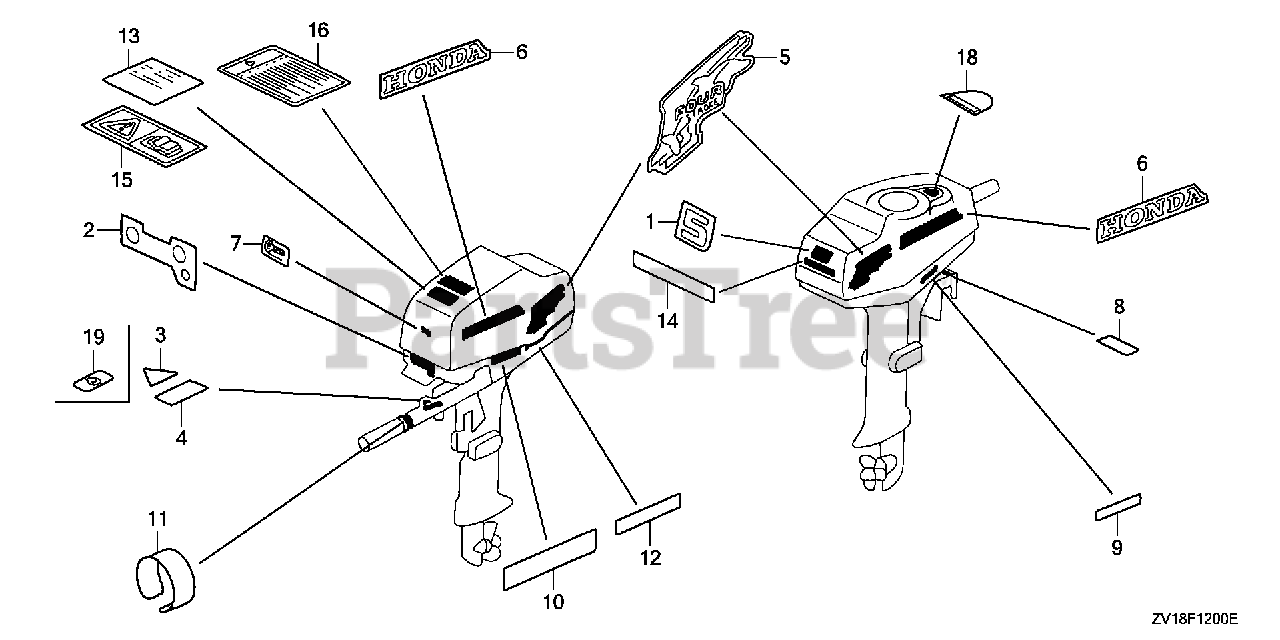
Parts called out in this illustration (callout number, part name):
1	MARK, RR. (5)
2	LABEL, INDICATION
3	MARK, EMERGENCY SWITCH INDICATION (ENGLISH)
4	MARK, SPARE CLIP (ENGLISH)
5	MARK, SIDE
6	MARK, SIDE STRIPE (HONDA)
9	MARK, CHANGE (JAPANESE/ENGLISH)
10	LABEL, OIL CAUTION (ENGLISH)
11	MARK, THROTTLE (ENGLISH)
12	LABEL, STORING CAUTION (ENGLISH)
13	LABEL, OPERATOR CAUTION (ENGLISH)
13	LABEL, WARNING OPERATOR (ENGLISH)
14	MARK, PROGRAMMED IGNITION
18	MARK, EMERGENCY START (E)
19	MARK, EMERGENCY SWITCH INDICATION
19	MARK, EMERGENCY SWITCH INDICATION (EU)
